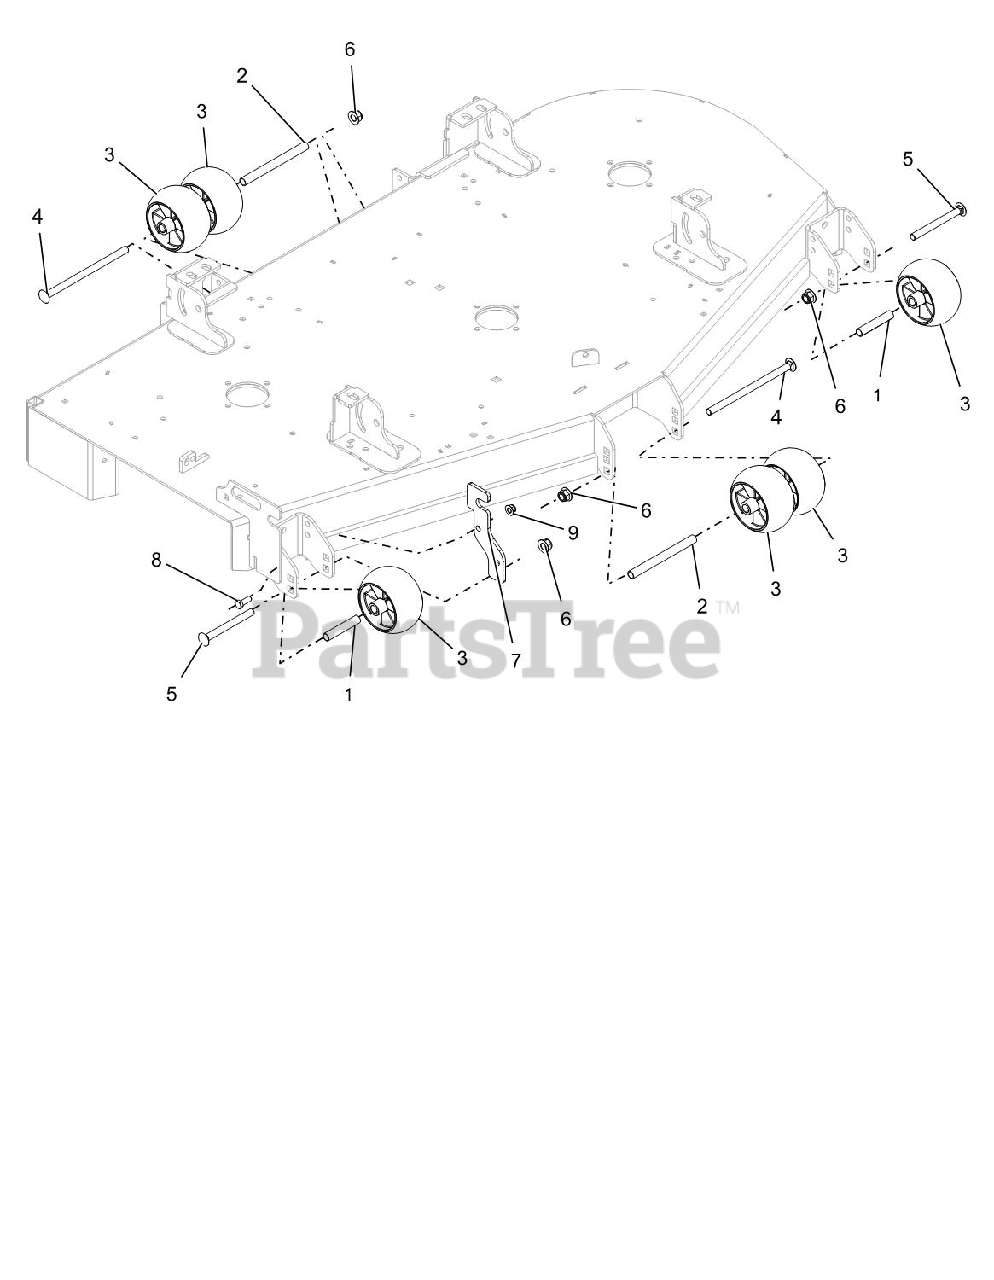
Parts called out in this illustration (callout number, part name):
1	SPACER, .510X.625X3.35
2	SPACER, .510 X .625 X 6.50
3	ANTI-SCALP WHEEL
4	BLT-RDHDSQNK .50-13X8.50 Y
5	BLT-RDHDSQNK .50-13X5.00 G5 YWZC
6	NUT-LK-NYL-FLG .50-13 YWZC
7	CHUTE STORAGE BRACKET-RED
8	BLT-HEX .38-16X1.00 GR5 YWZC
9	NUT-LK-NYL-FLG .38-16 YWZC
